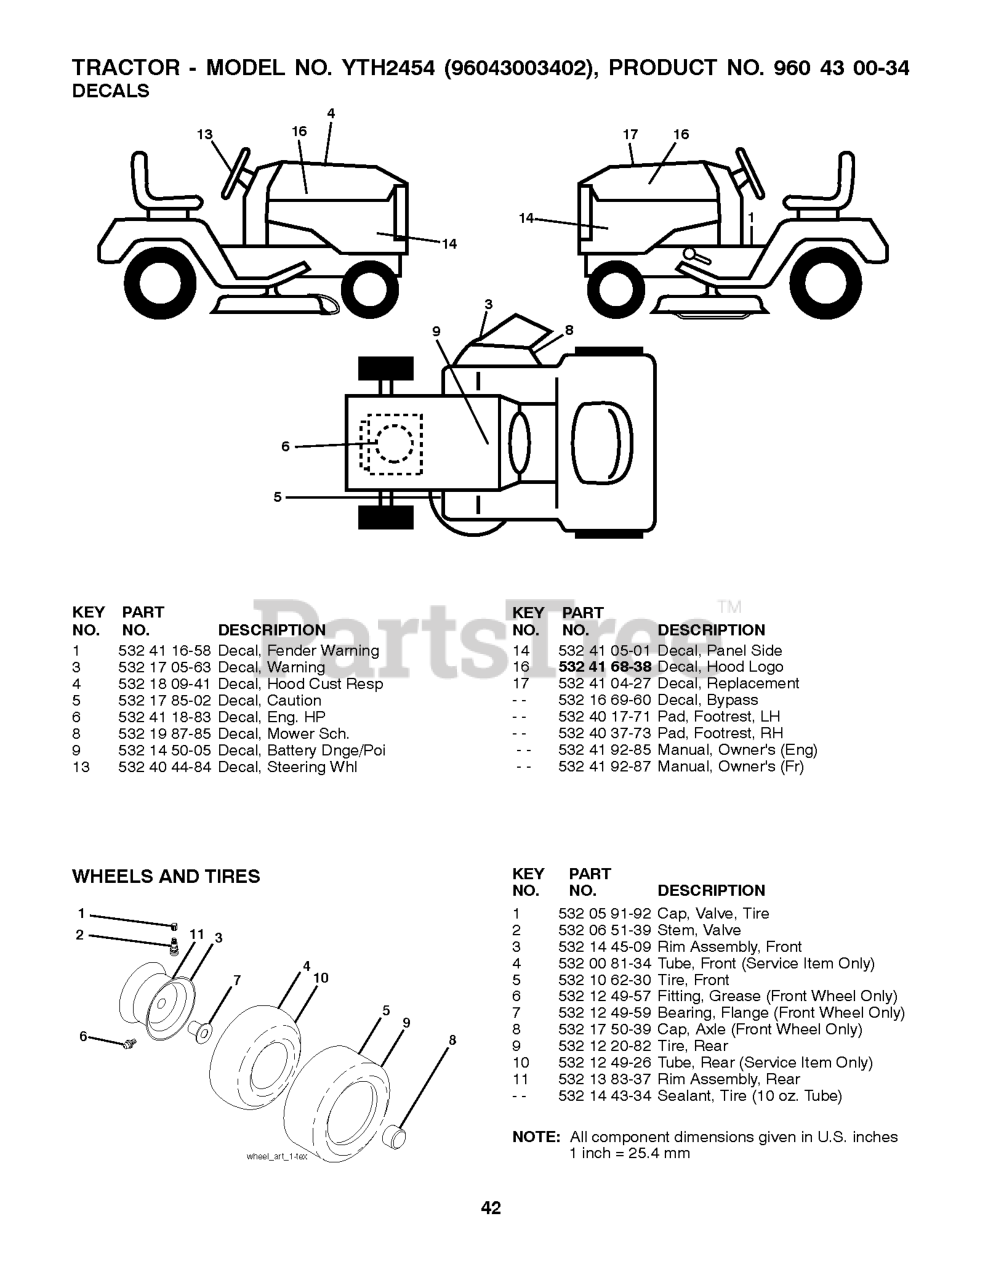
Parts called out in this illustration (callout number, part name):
1	DECAL.FENDER.WARNING.ENG
3	DECAL.WARN.KEEP.HAND.AWAY
4	DECAL HOOD CUST. RESP.
5	DECAL CLUTCH/BRAKE
6	DECAL.ENG.B&S.24HPINTK.LP.GEN
8	DECAL.MOWER.SCH.48/54
9	DECAL BTRY SYMBOLS
13	DECAL.WHEEL.STRG.LGN.H
14	DECAL PANEL
16	DECAL.HOOD.LOGO.HUSQVARNA
17	DECAL.RPL.BS.24.INTK.TGW.54.TT
